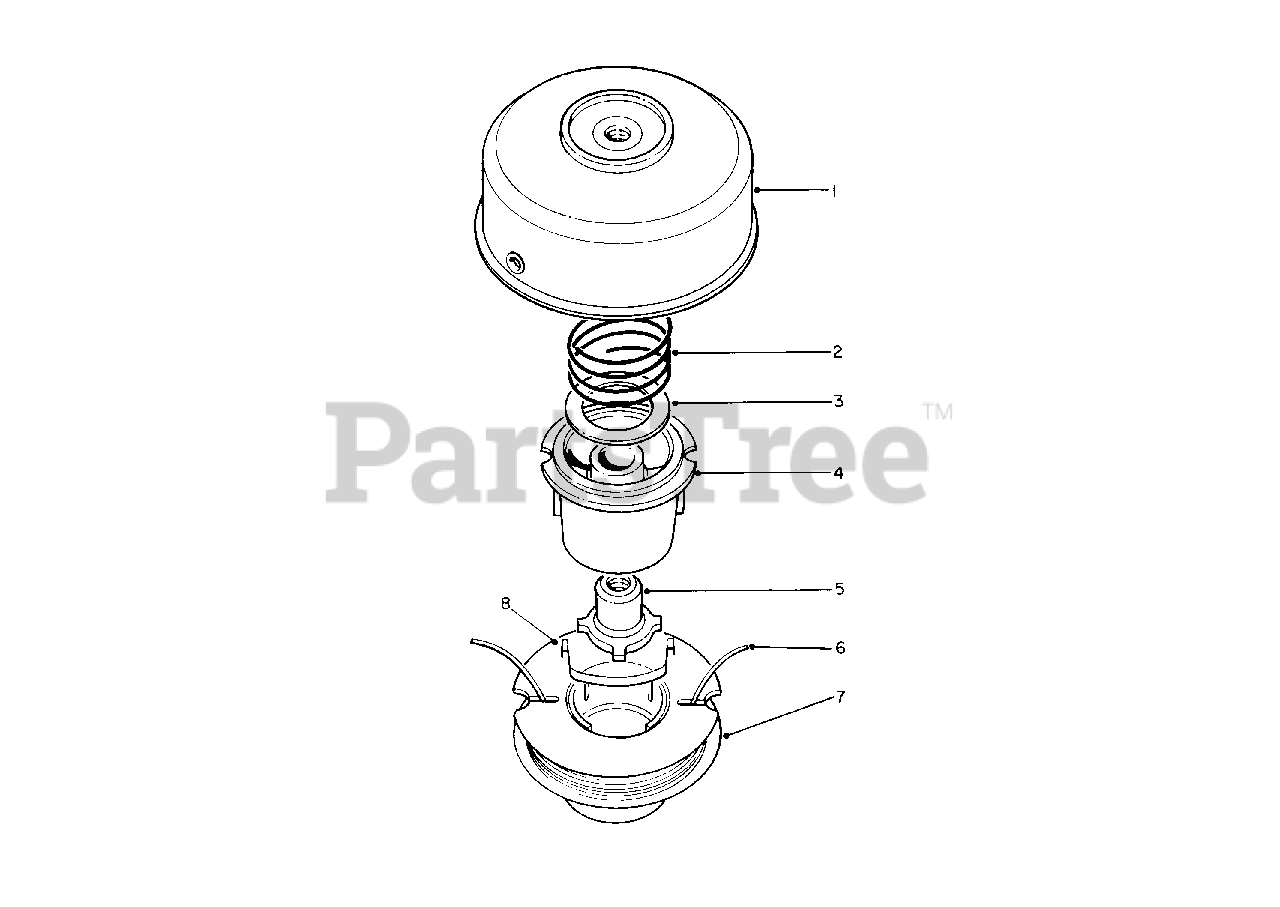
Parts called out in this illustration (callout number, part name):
1	Drum w/Eyelets
4	Spool Core
5	Driver L.H.
7	Spool Prewound .08 Dia. 38' (Incl. Ref. #8)
8	Saddle-Spool Cap
